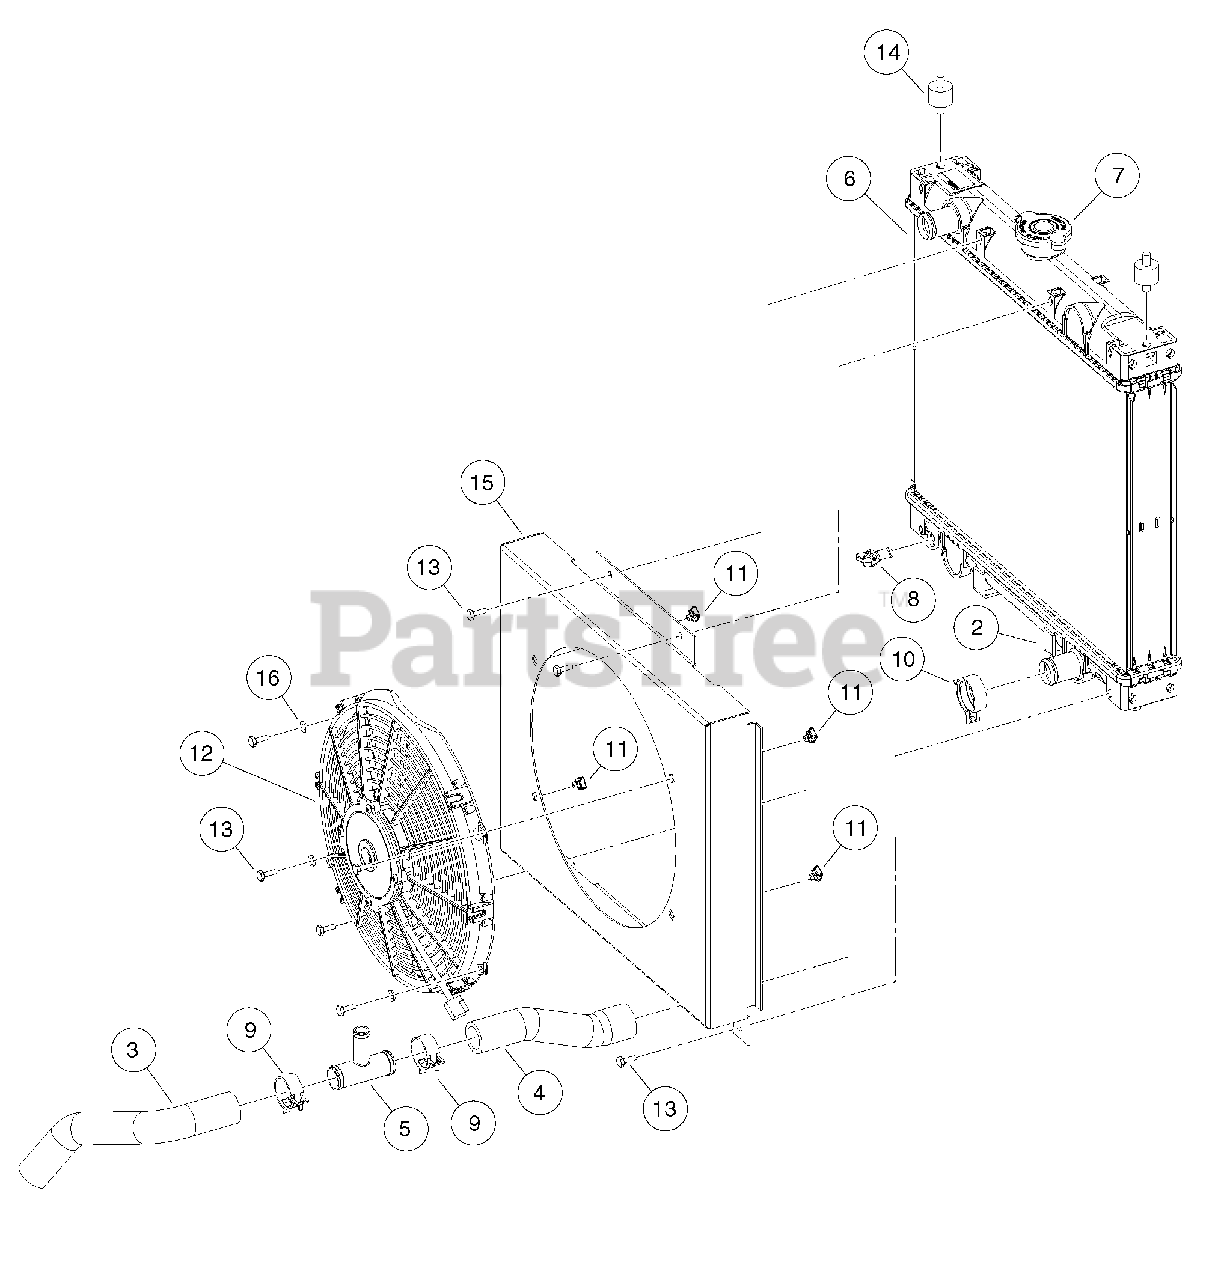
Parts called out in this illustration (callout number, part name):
1	Asm, Radiator
3	Hose, Coolant Lower Pipe
4	Hose, Coolant Lower Rad
5	Tee, Coolant Fill
6	Exchanger, Engine Coolant
7	Cap, Radiator
8	Drain Cock, Radiator
9	Clamp, Hose, Ctb 35mm
10	Clamp, Hose, Ctb 38mm
11	Nut, Self Retaining
12	Fan, Cooling 12 In Elect
13	Bolt, M6 X 1 X 16 Loctite
14	Isolator, Twin-Stud
15	Shroud, Radiator Fan
16	Washer, M6
